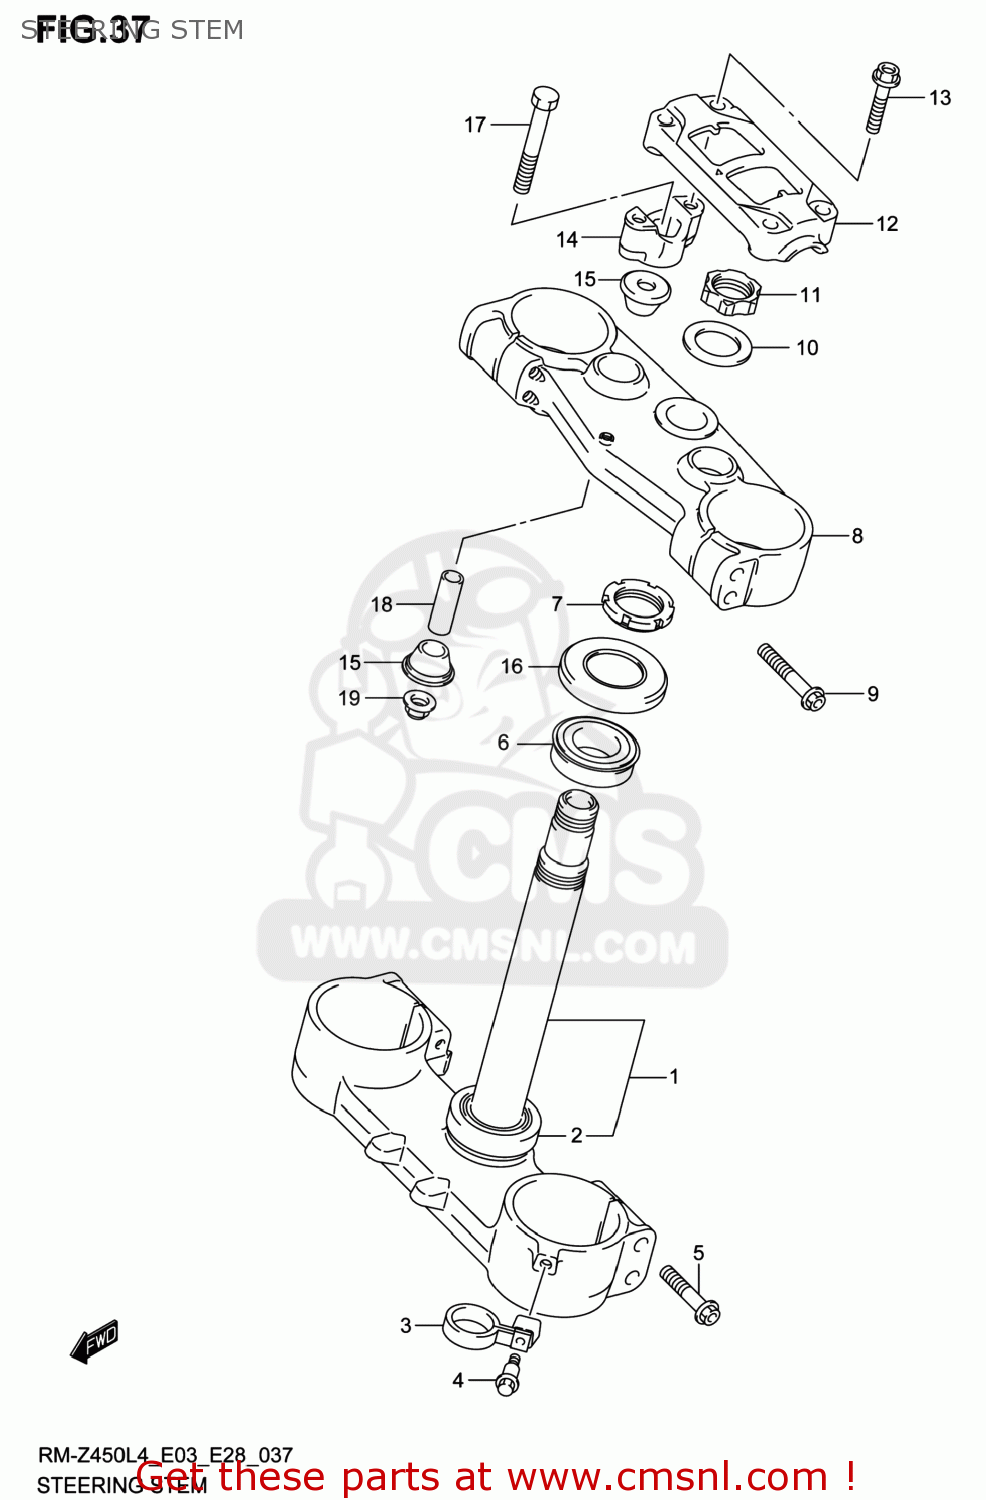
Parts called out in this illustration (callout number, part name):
1	STEM,STEERING
2	BEARING(30X52X16)
3	GUIDE,FR BRAKE HOSE
4	BOLT(6X20.5)
5	BOLT
6	BEARING(30X52X16)
7	NUT,STEERING
8	HEAD,STEERING STEM
9	BOLT
10	WASHER,STEM HEAD
11	NUT,STEM HEAD
12	HOLDER,HANDLE
13	BOLT
14	HOLDER,HANDLE
15	CUSHION,RUBBER
16	COVER,STEERING UPR
17	BOLT,HANDLE HOLDER
18	SPACER
19	NUT
